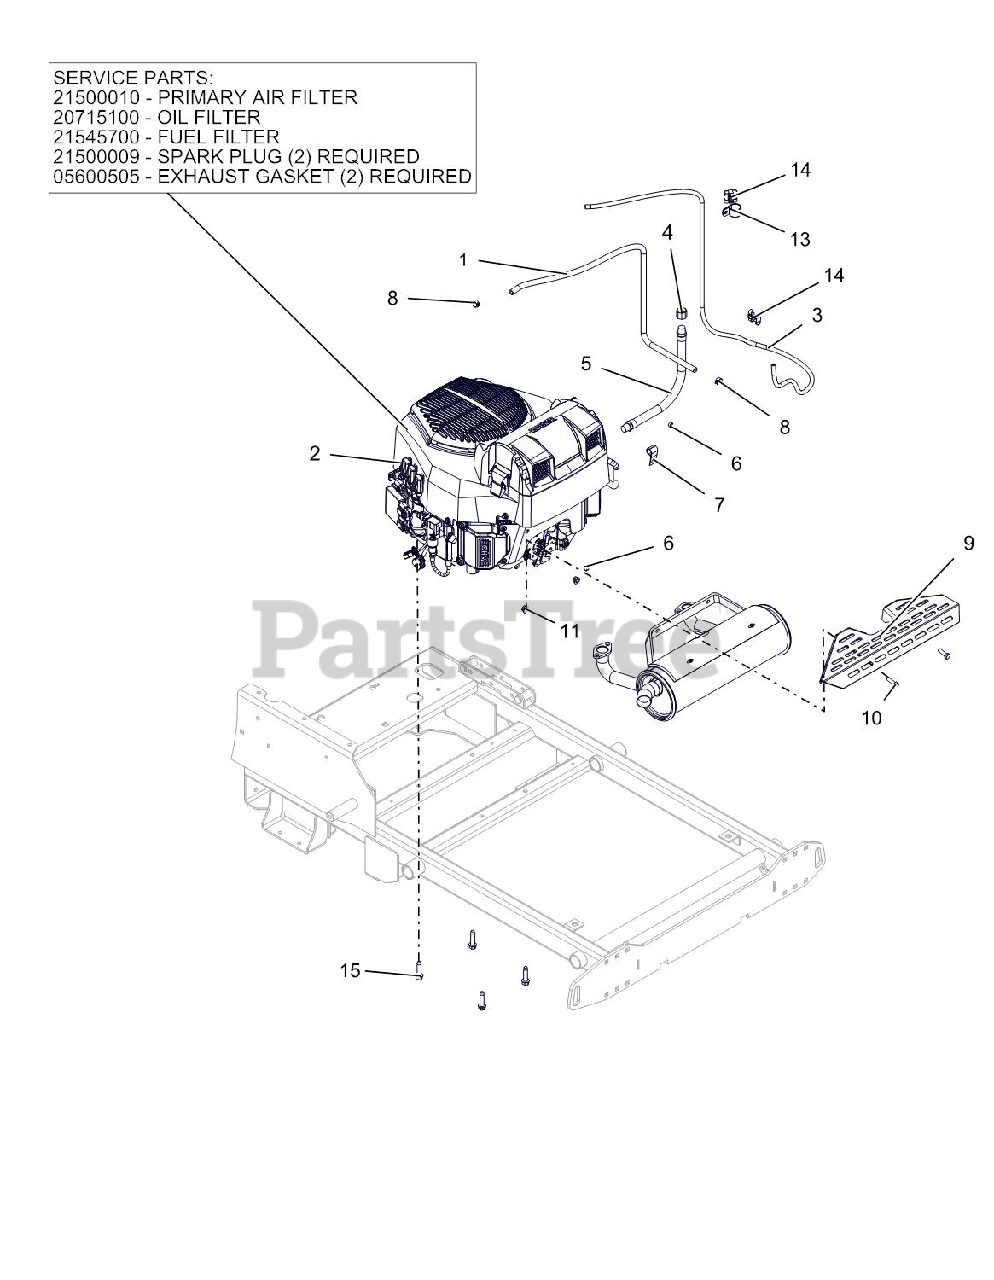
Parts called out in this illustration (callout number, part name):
1	HOSE, .25 LOW-PERM BULK GAS
2	GASKET, MUFFLER COURAGE TWIN
2	AIR CLEANER, KOHLER CONFIDANT
2	FILTER-FUEL KOHLER COURAGE PRO
2	PLUG, SPARK KOHLER
2	OIL FILTER KOHLER
2	ENGINE, KOHLER EZT725
3	HOSE, .188 LOW-PERM BULK GAS
4	PIPE CAP 3/8 NPT FEMALE
5	HOSE,HYD .38-14-0K M6N0-M6N0
6	CLAMP-HOSE, SPRING .188
8	CLAMP, FUEL LINE
9	GUARD, MUFFLER
10	BLT-HEX .31-18X1.00 GR5 YWZC
11	NUT-LK-NYL-FLG .31-18 YWZC
13	CLAMP, COUSHIONED STEEL REV
14	CLIP, T, .38-.50
15	SCR-TAP .38-16X1.50 HWH TR YZ
